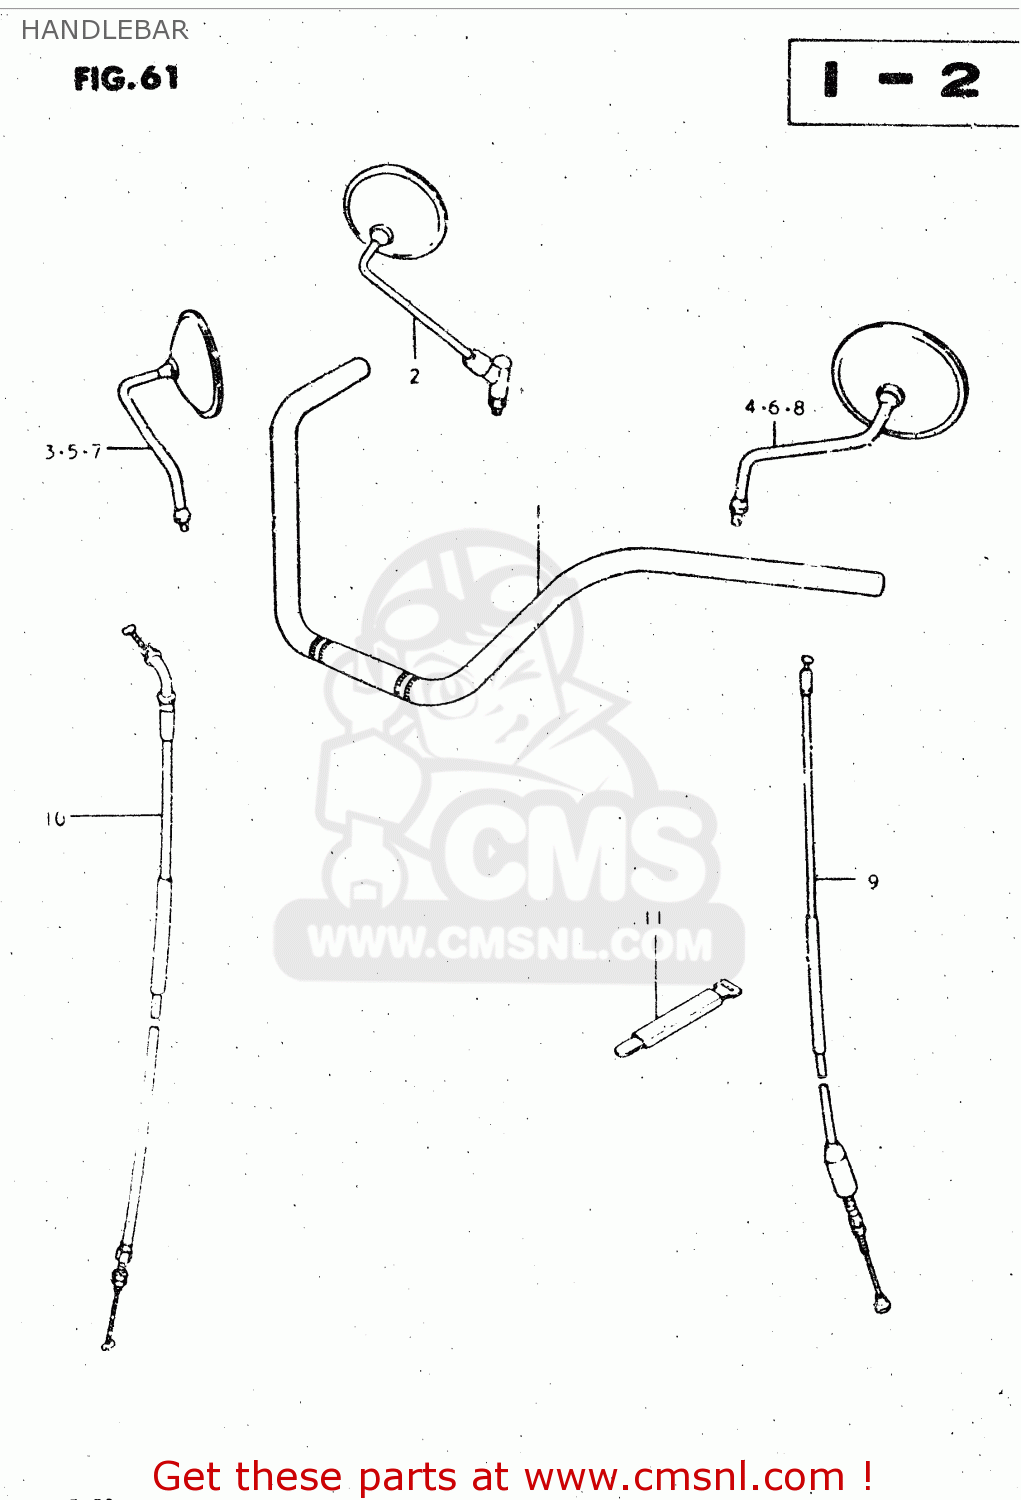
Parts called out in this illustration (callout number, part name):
1	HANDLEBAR
2	MIRROR ASSY,RH
3	MIRROR ASSEMBLY,RIGHT
4	MIRROR ASSEMBLY,LEFT
5	MIRROR ASSY,RH
6	MIRROR ASSY,LH
7	MIRROR, REAR VIEW RH
8	MIRROR, REAR VIEW LH
9	CABLE ASSEMBLY,CLUTCH
10	CABLE ASSEMBLY,THROTTLE
11	CLAMP
